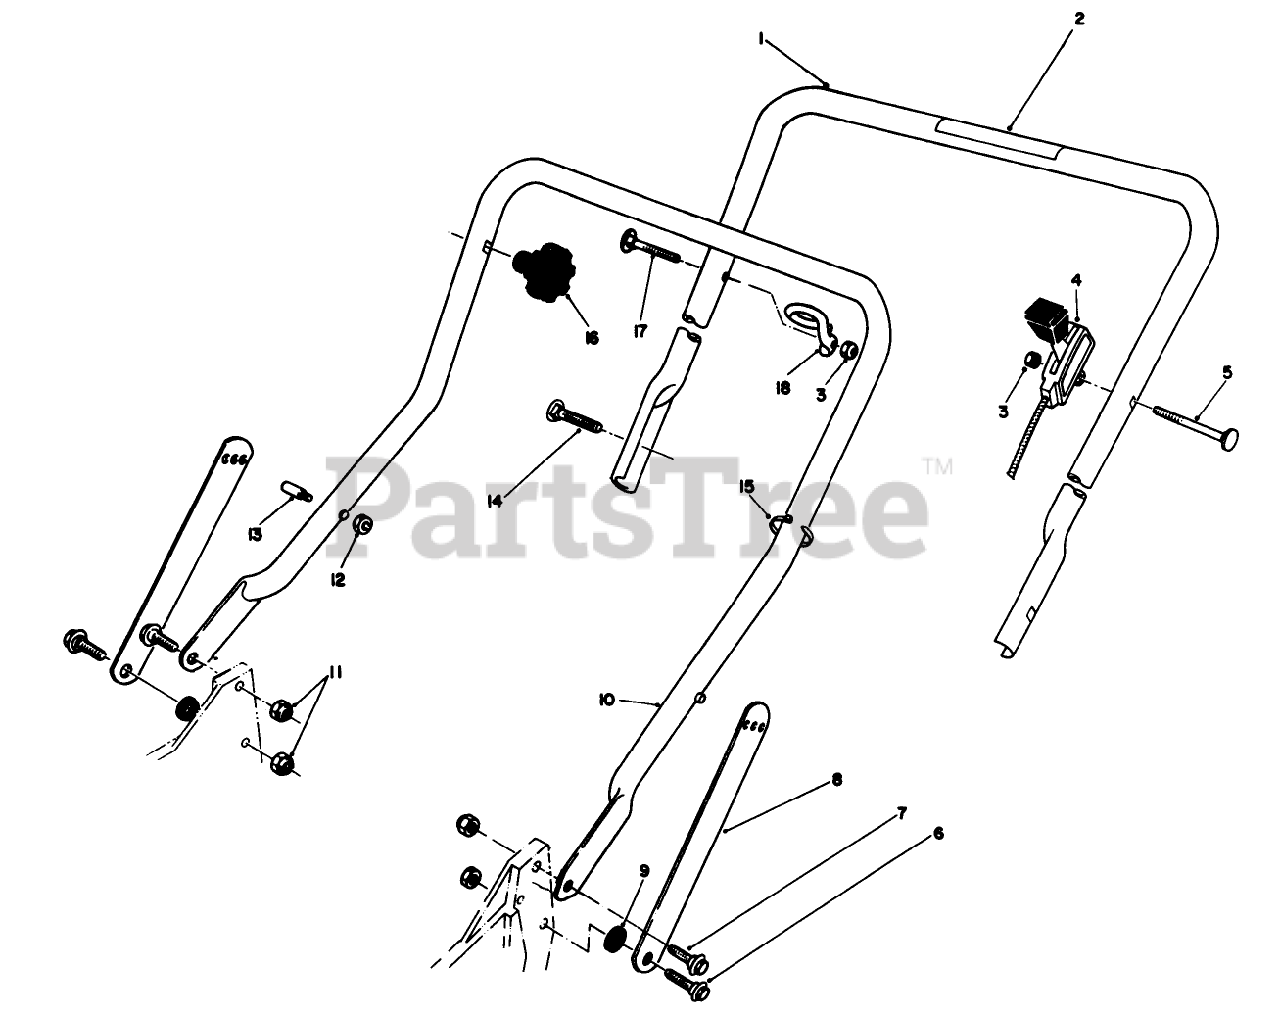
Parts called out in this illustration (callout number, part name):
3	NUT-LOCK, NI
5	SCREW-HANDLE
6	SCREW-SHOULDER
7	SCREW-SHOULDER
9	SPACER
11	NUT-LOCK, NI
12	NUT-LOCK, NI
13	HANDLE PIN
15	TIE-CABLE
17	HANDLE SCREW
